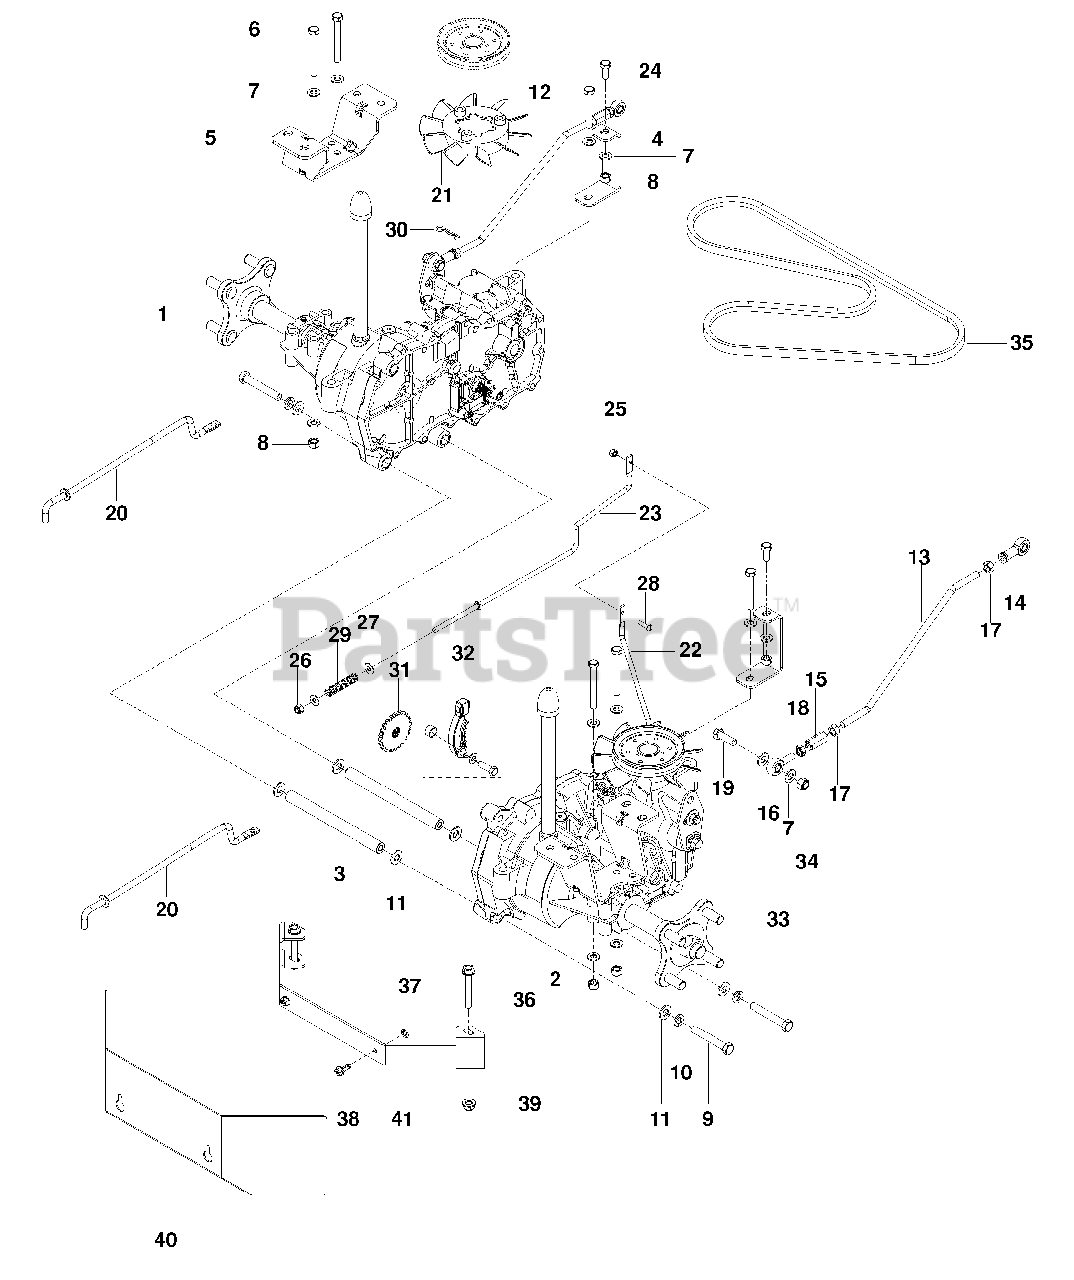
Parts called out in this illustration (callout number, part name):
3	SPACER TUBE
4	SUPPORT, EZT FRT
5	MOUNT, EZT RR BLK
6	HCS 5/16-18 x 2 3/4
7	WASHER 5/16 SAE FLT
8	NUT 5/16-18 HEX NYLOC
9	HCS 3/8-16 x 2 1/2
10	WASHER 3/8 SPLT LK
11	WASHER 3/8 SAE FLT
12	HCS 5/16-18 x 2 1/4
13	ROD, MOTION CONTROL
14	ROD END RT
15	COUPLER, ROD END
16	ROD END MALE LT
17	NUT 5/16-24 HEX
18	NUT 5/16-24 HEX JAM LH
19	HCS 5/16-18 x 1
20	LINK ARM, BYPASS
21	BLADE, FAN
22	ROD, EZT BRAKE LT
23	ROD, EZT BRAKE RT
24	HCS 5/16-18 x 3/4
25	NUT 10-24 HEX NYLOC
26	NUT 1/4-20 HEX NYLOC
27	WASHER 1/4 SAE FLT
28	SCREW 10-24 x 3/4 SLTD RD
29	SPRING, BRAKE ROD
30	HAIRPIN, COTTER
31	COG, BRAKE DISC
32	BRAKE ARM KIT
33	HUB KIT
34	NUT 5/16-18 NYLOC INSERT
36	HHFS 5/16-18 x 2 1/4
37	PALNUT 1/4
38	SCREW 1/4-20 x 5/8 TRDROLL
39	NUT 5/16-18 FLANGE NYLOC
40	GUARD, DRIVE PULLEY
41	BRACKET, GUARD
